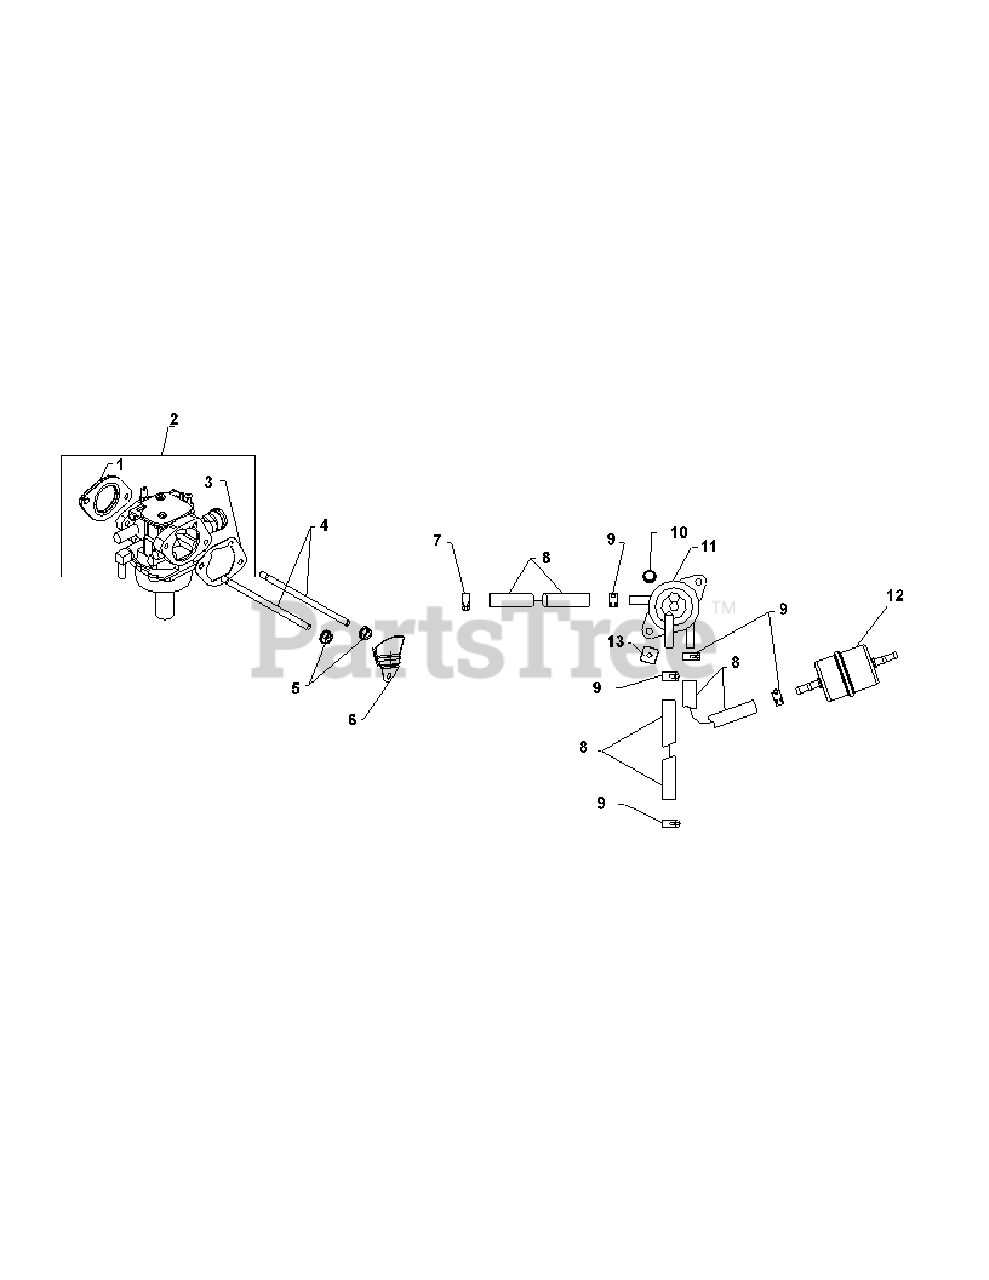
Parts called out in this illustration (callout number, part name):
1	Gasket, Carburetor
2	Kit, Carburetor W/Gaskets
3	Gasket, Air Cleaner Base
4	Stud,M6X1.0X96
5	Nut, Flg M6X1.0
6	Baffle, Spit-Back Cup Use 24 063 105-S
7	Clamp, Hose 1/2" Use 25 237 14-S
8	Line, Fuel
9	Clamp, Hose 1/2'' Use 25 237 31-S
10	Screw, Tap M6X1.7X18
12	Filter, Fuel
13	Nut, Plastic - Black
